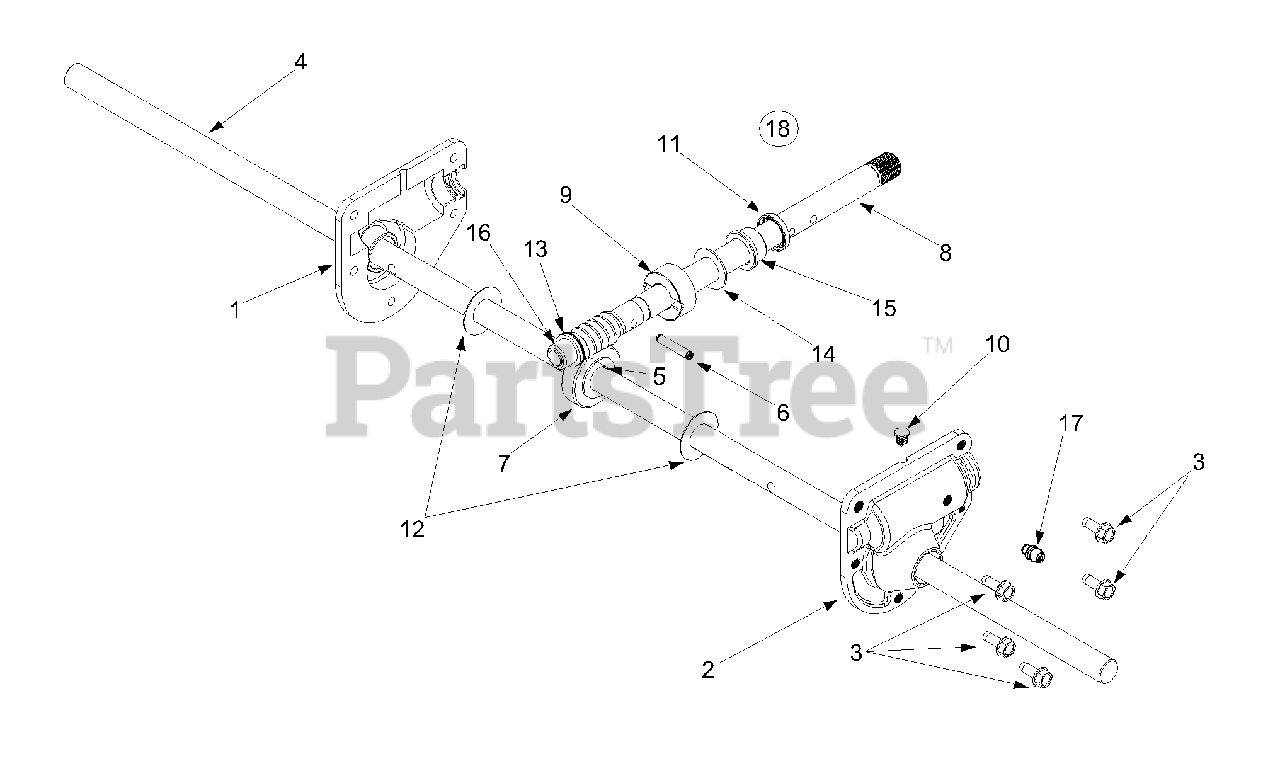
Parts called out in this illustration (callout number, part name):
1	RH Housing
2	LH Housing
3	Self Tapping Screw, 1/4-20 x .75
4	Spiral Axle 28"
5	Hi-Pro Key, 3/16 x 5/8
6	Spring Spiral Pin, .25 x 1.25
7	Worm Gear, 20-tooth
8	Worm Shaft
9	Thrust Collar
10	Grease Plug
11	Grease Seal
12	Flat Washer, .76 x 1.5 x .030
13	Flat Washer, .508 x 1.0 x .020
14	Flat Washer, .76 x 1.5 x .060
15	Flange Bearing, .75 x 1.0 x .59
16	Flange Bearing, .503 ID x .75 OD
17	Lube Fitting, 3/16 Drive
18	Gear Assembly Complete, 28"
